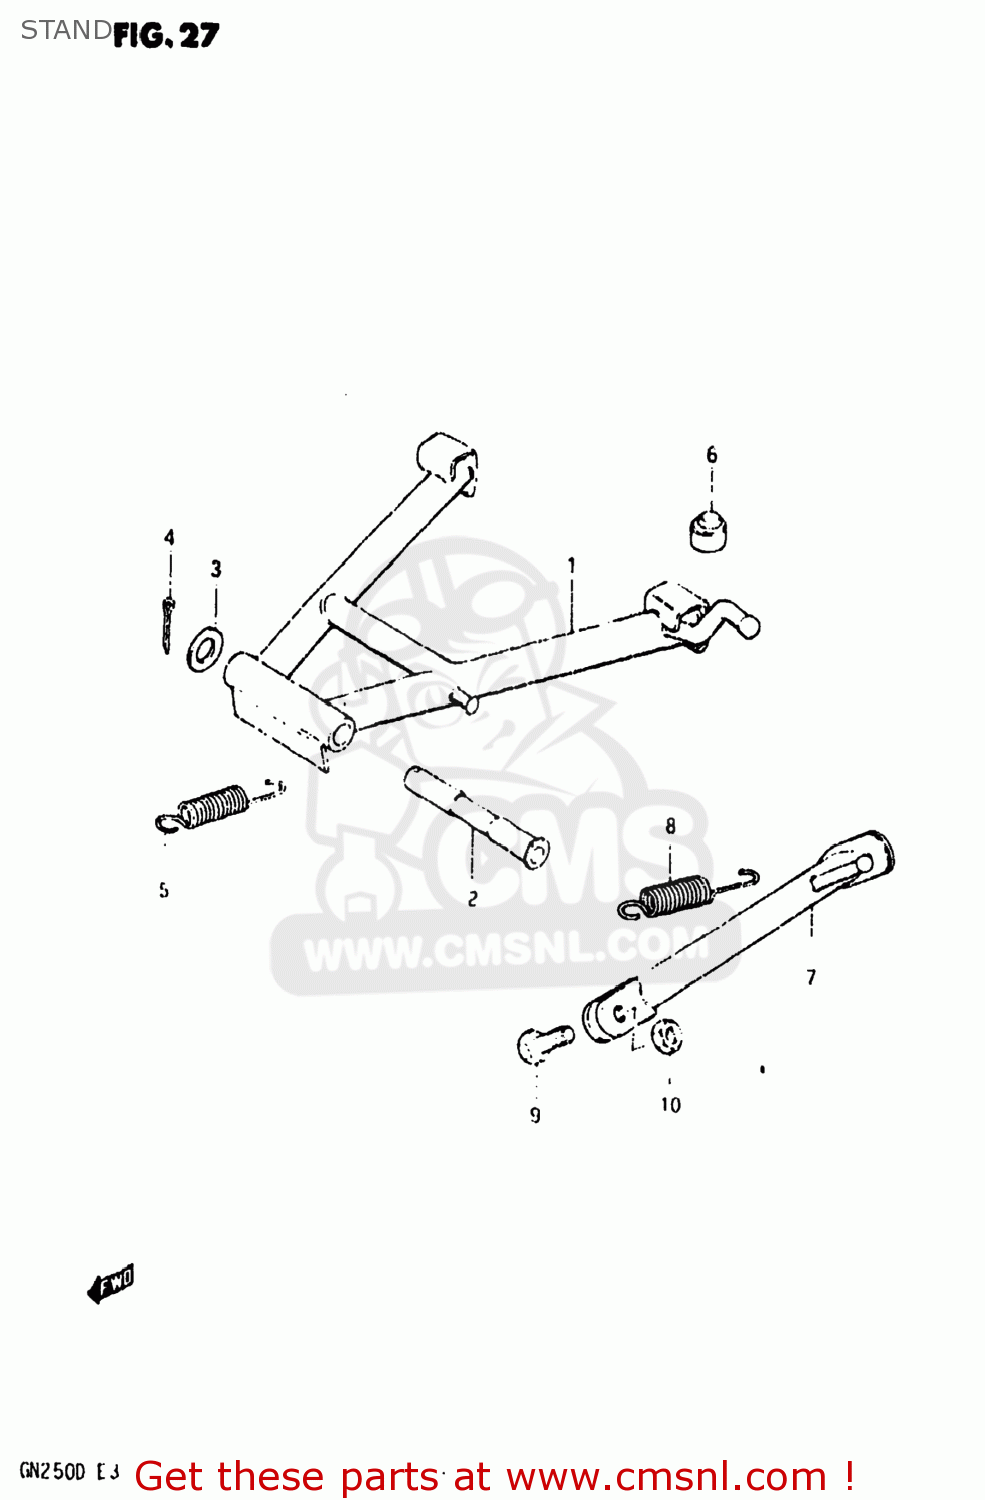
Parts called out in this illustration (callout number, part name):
1	STAND,CTR
2	SHAFT,CENTER STAND
3	WASHER(16.5X32X2.3)
4	COTTER PIN
5	SPRING
6	CUSHION
7	STAND,SIDE
8	SPRING
9	BOLT(10X30)
10	NUT
